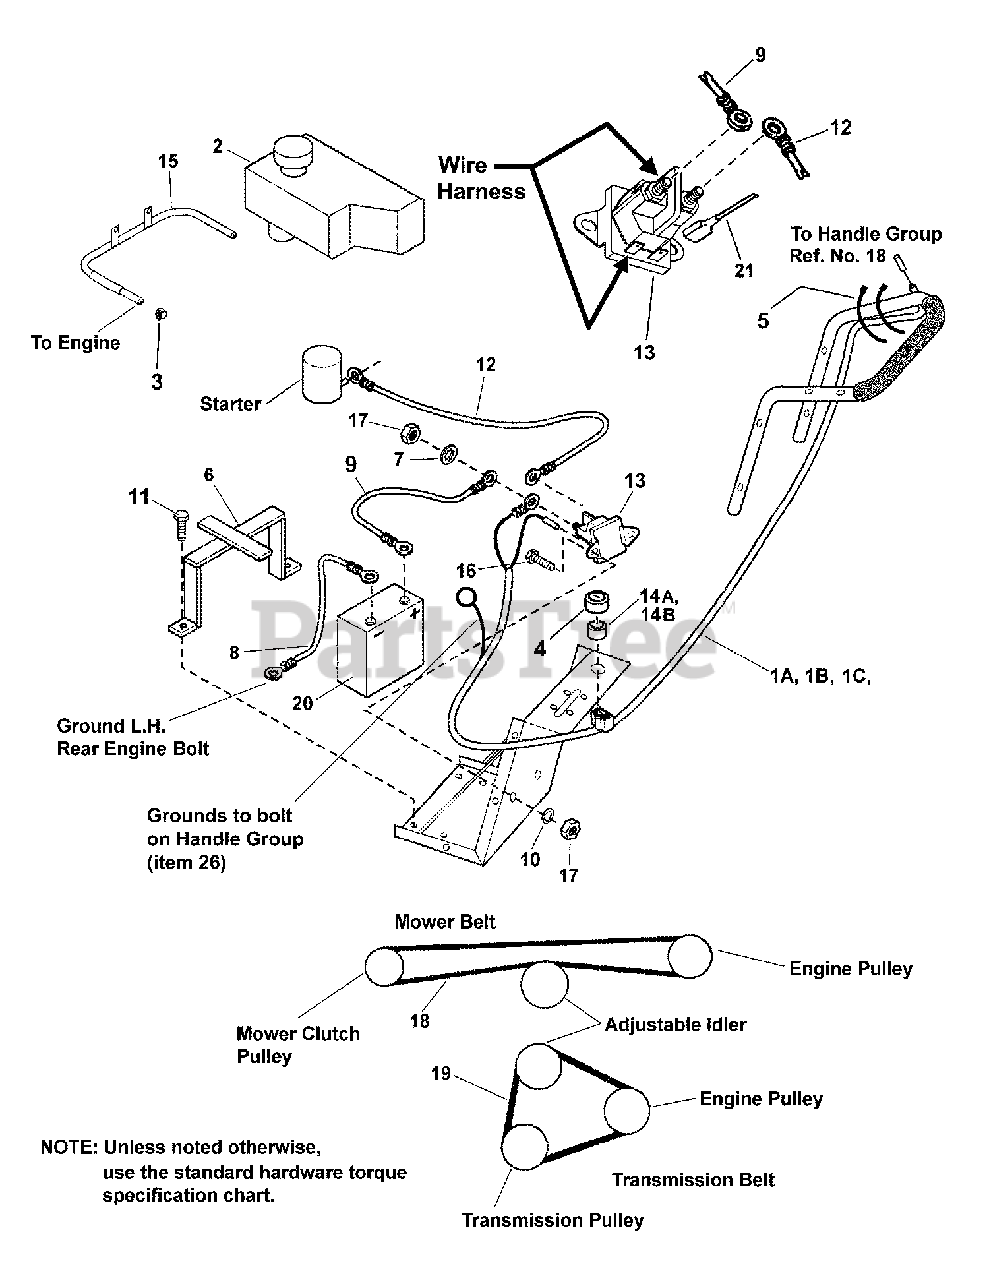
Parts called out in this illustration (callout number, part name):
1A	WIRE HARNESS, Briggs
1B	WIRE HARNESS, Kawasaki
1C	WIRING HARNESS, Honda
2	FUEL TANK, Auxilliary
3	CLAMP, Fuel Hose
4	BEZEL
5	CABLE TIE, 7"
6	BRACKET, Battery Hold Down
7	WASHER, 1/4" Internal Tooth Lock
8	CABLE, Battery Negative to Ground
9	CABLE, Battery Positive to Solenoid
10	WASHER, 1/4 Split Lock
11	SCREW, Tek #12 x 3/4" Hex Head Cap
12	CABLE, Solenoid to Starter
13	SOLENOID, Super Trombetta - 2 Terminal
14A	SWITCH, Keyed Start
14B	SWITCH, Ignition, 2-Pole
15	FUEL LINE w/Clamps, 15HP Kaw & 16HP B&S (use 7072545)
15	FUEL LINE w/Clamps, 13HP Honda
16	SCREW, 1/4-20 x 3/4" Hex Head Cap, GR 5
17	NUT, 1/4-20 Hex, GR 5 or B
18	BELT, Blade Clutch (5L Sect.; 67.40 effective length)
19	BELT, Transmission (AX Sect.; 30.10 effective length)
20	BATTERY, 12V, 3 Amp, 190 Cold Cranking Amp (Includes Drain Tube)
21	GROUND WIRE, 16 Ga., Green, 19" long
